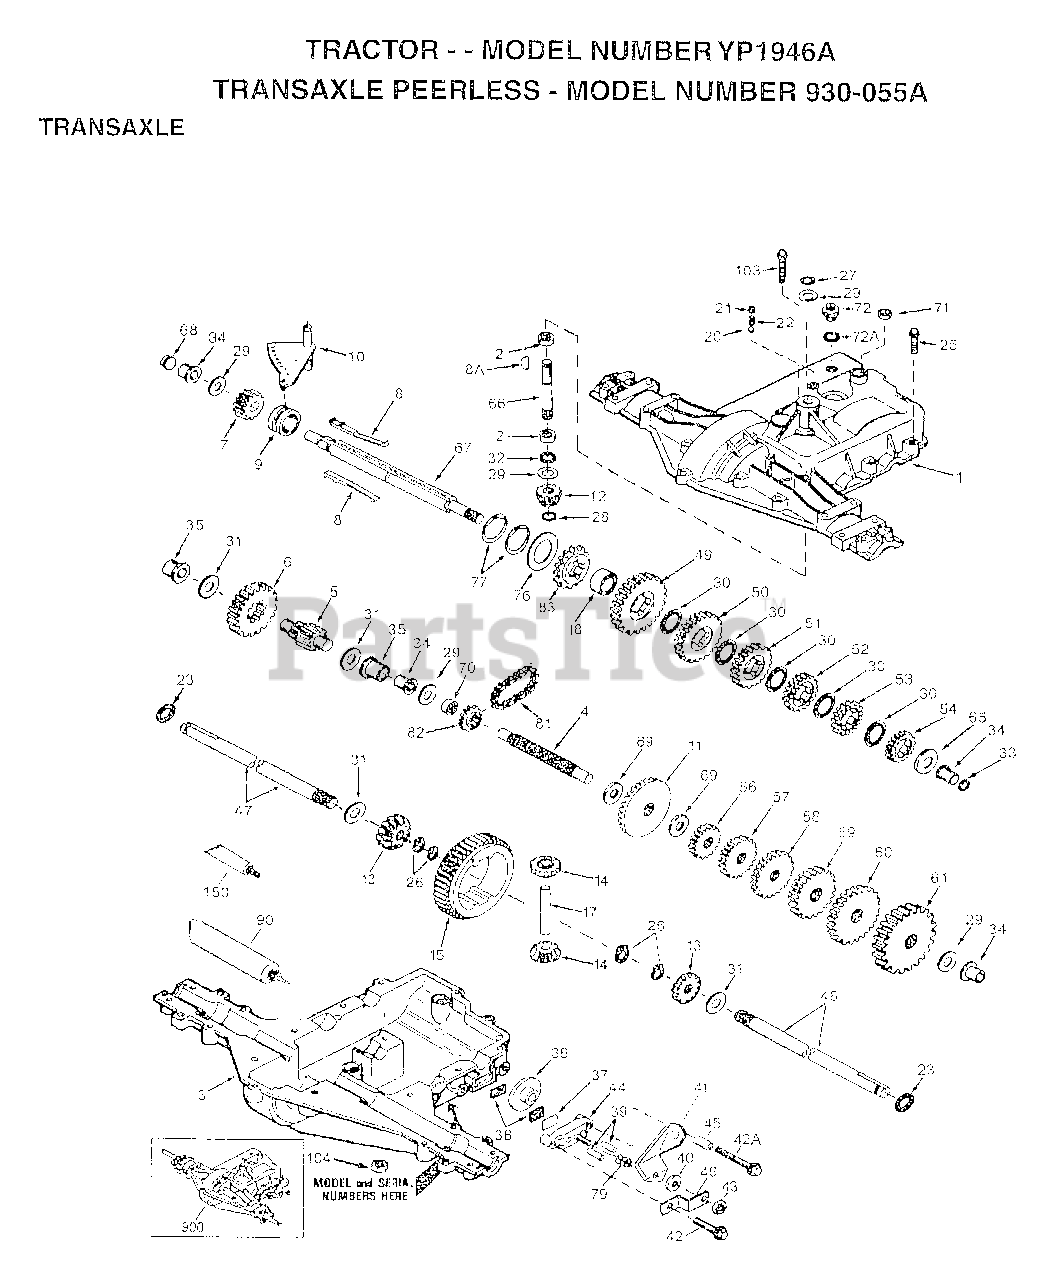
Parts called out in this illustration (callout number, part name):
1	TRANSAXLE COVER
2	BEARING, NEEDLE
3	TRANSAXLE CASE
4	SHAFT, COUNTER
5	OUTPUT SHAFT AND PINION
6	GEAR, OUTPUT
7	GEAR, SPUR, 15 TEETH
8A	KEY, WOODRUFF
9	COLLAR, SHIFTER
10	ROD & FORK ASSY, SHIFT
11	GEAR, BEVEL, 42 TEETH
12	BEVEL PINION, INPUT
13	GEAR, BEVEL
14	GEAR, BEVEL, PINION
18	SPACER, NEUTRAL
20	BALL STEEL, 5/16" DIA.
21	SCREW, 3/8-16 X 3/8"
25	SCREW, 1/4-20 X 1-1/4
26	RING RETAINER
27	RING, RETAINER
28	RETAINING RING
29	WASHER THRUST
30	WASHER THRUST
33	SEAL, SQUARE CUT
34	BUSHING, FLANGED
35	BUSHING, FLANGED
36	DISK, BRAKE
37	PLATE BRAKE PAD
41	BRAKE LEVER
42	SCREW, 1/4-20 X 1-1/4
42A	SCREW, 1/4-20 X 2-1/4
43	LOCKNUT 5/16-24
44	HOLDER BRAKE PAD
46	BRKT BRAKE LEVER
49	GEAR, SPUR, 37 TEETH
50	GEAR, SPUR, 35 TEETH
51	GEAR, SPUR, 30 TEETH
52	GEAR, SPUR, 25 TEETH
53	GEAR, SPUR, 22 TEETH
54	GEAR, SPUR, 19T
56	GEAR, SPUR, 12 TEETH
57	GEAR, SPUR, 15 TEETH
58	GEAR, SPUR, 20 TEETH
59	GEAR, SPUR, 25 TEETH
60	GEAR, SPUR, 28 TEETH
61	GEAR, SPUR, 31 TEETH
65	WASHER, THRUST
66	SHAFT, INPUT
67	SHAFT, BRAKE, 4 KEYED
69	WASHER THRUST
71	SEAL SQUARE CUT
72	THREADED PLUG 9/16-18
76	WASHER, THRUST
77	INVERTED RETAINING RING
81	CHAIN, ROLLER
82	SPROCKET 9T
83	SPROCKET 18T (REV)
90	GREASE BENTONITE, 32 OZ.
150	GASKET ELIMINATOR
900	REPLACEMENT TRANSAXLE
